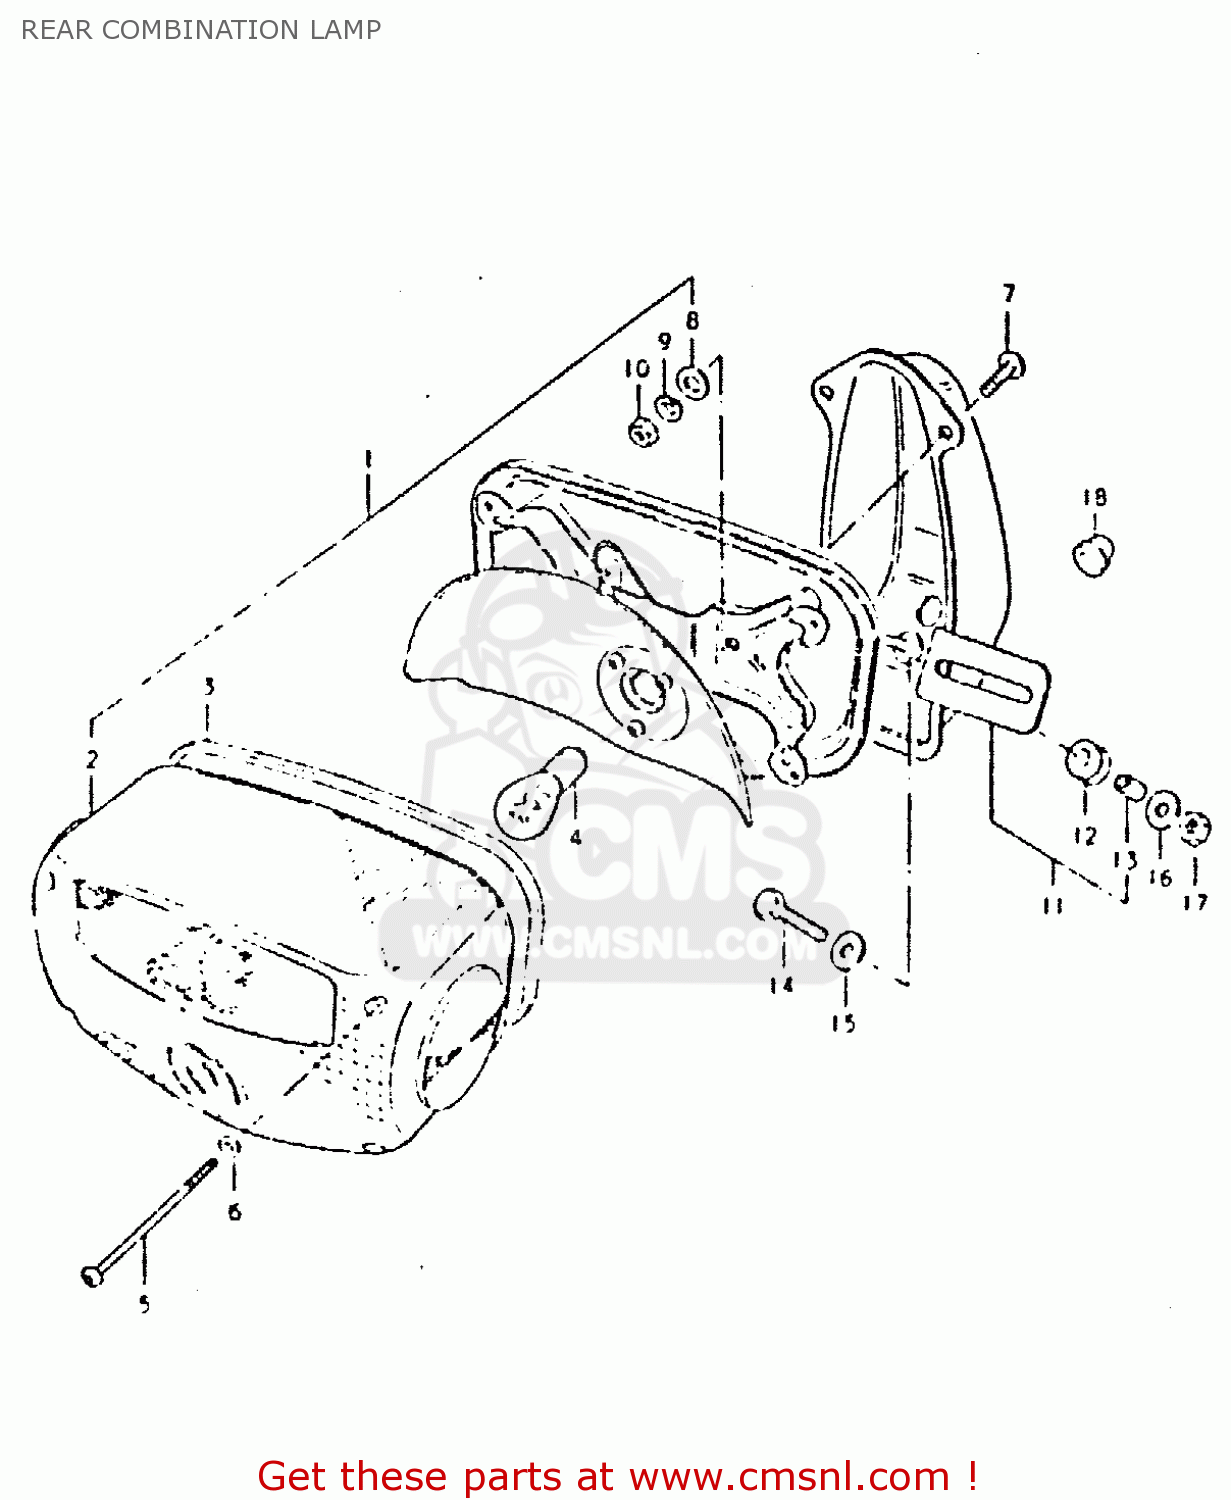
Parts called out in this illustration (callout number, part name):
1	LAMP UNIT, TAIL
2	LENS,REAR COMBINATION LAMP
3	GASKET (NAS)
4	BULB (12V, 21/5W)
5	SCREW (4X55)
6	GASKET (NAS)
7	SCREW 6X12
8	WASHER
9	LOCK WASHER
10	NUT
11	BRACKET ASSY
12	CUSHION
13	SPACER
14	BOLT
15	WASHER (6.5X20X1.2)
16	WASHER
17	NUT
18	GROMMET
